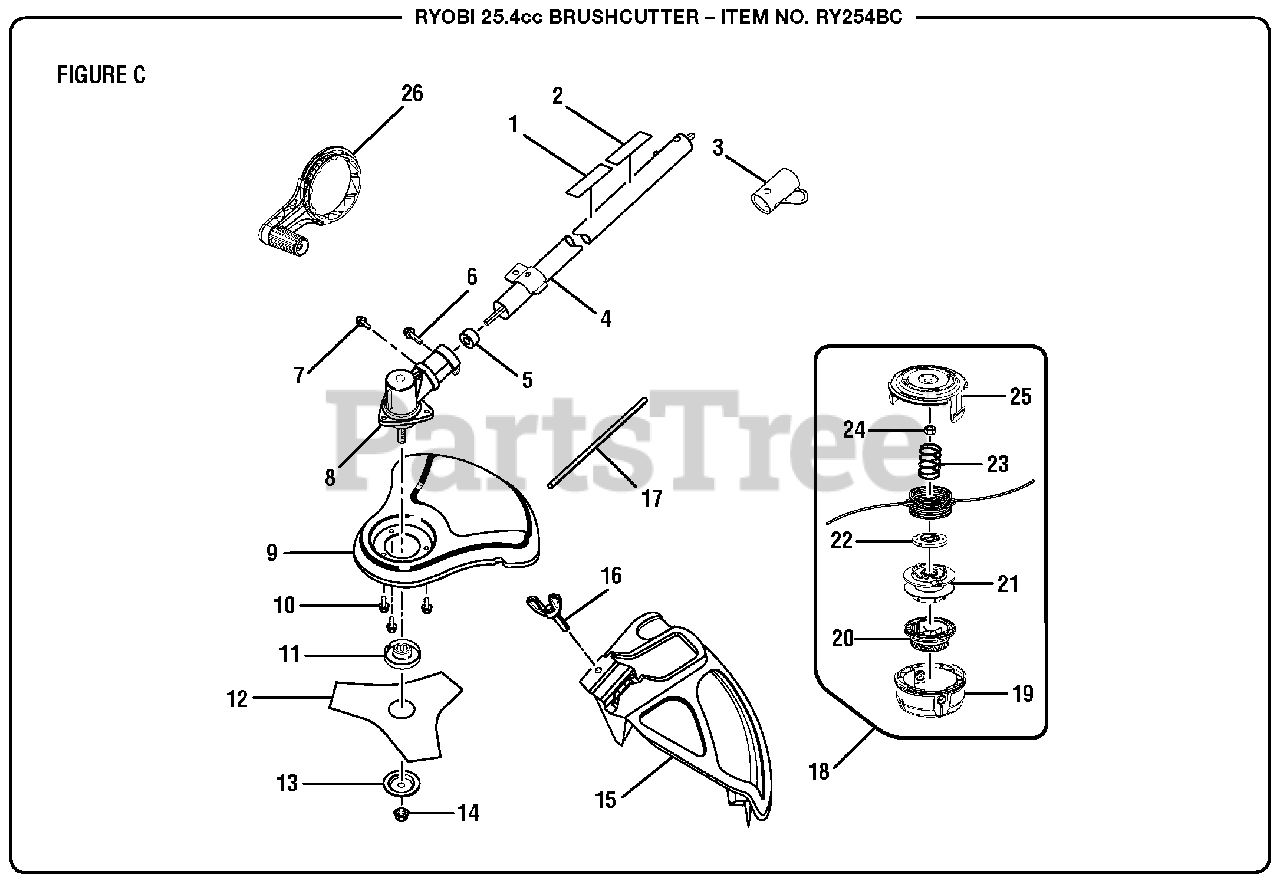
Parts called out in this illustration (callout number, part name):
1	Expand-it Label
2	Brushcutter Safety Label
3	Storage Hanger Cap
4	Lower Straight Shaft Boom Assembly
6	Screw (1/4-20 x 1-1/4 in., Hex Washer Hd. S.T.)
7	Screw (10-24 x 5/8 in., Hex Washer Hd. S.T.)
8	Gear Case Assembly
9	Brushcutter Guard
10	Screw w/Washer (10-24 x 1/2 in., Slotted Hex Hd.)
11	Flanged Washer
13	Cupped Washer
14	Lock Nut (M8 x 1.25 in., Left Hand Threads)
15	Grass Deflector Assembly
16	Screw (1/4-20 x 7/8 in.)
17	Gear Head Locking Tool
18	Trimmer Head Assembly (.095)
19	Lower Housing
20	Bump Knob (Green)
22	String Guide
23	Compression Spring
24	Hex Nut (M8, L.H. Thread)
25	Upper Housing
26	Crank Handle Assembly
